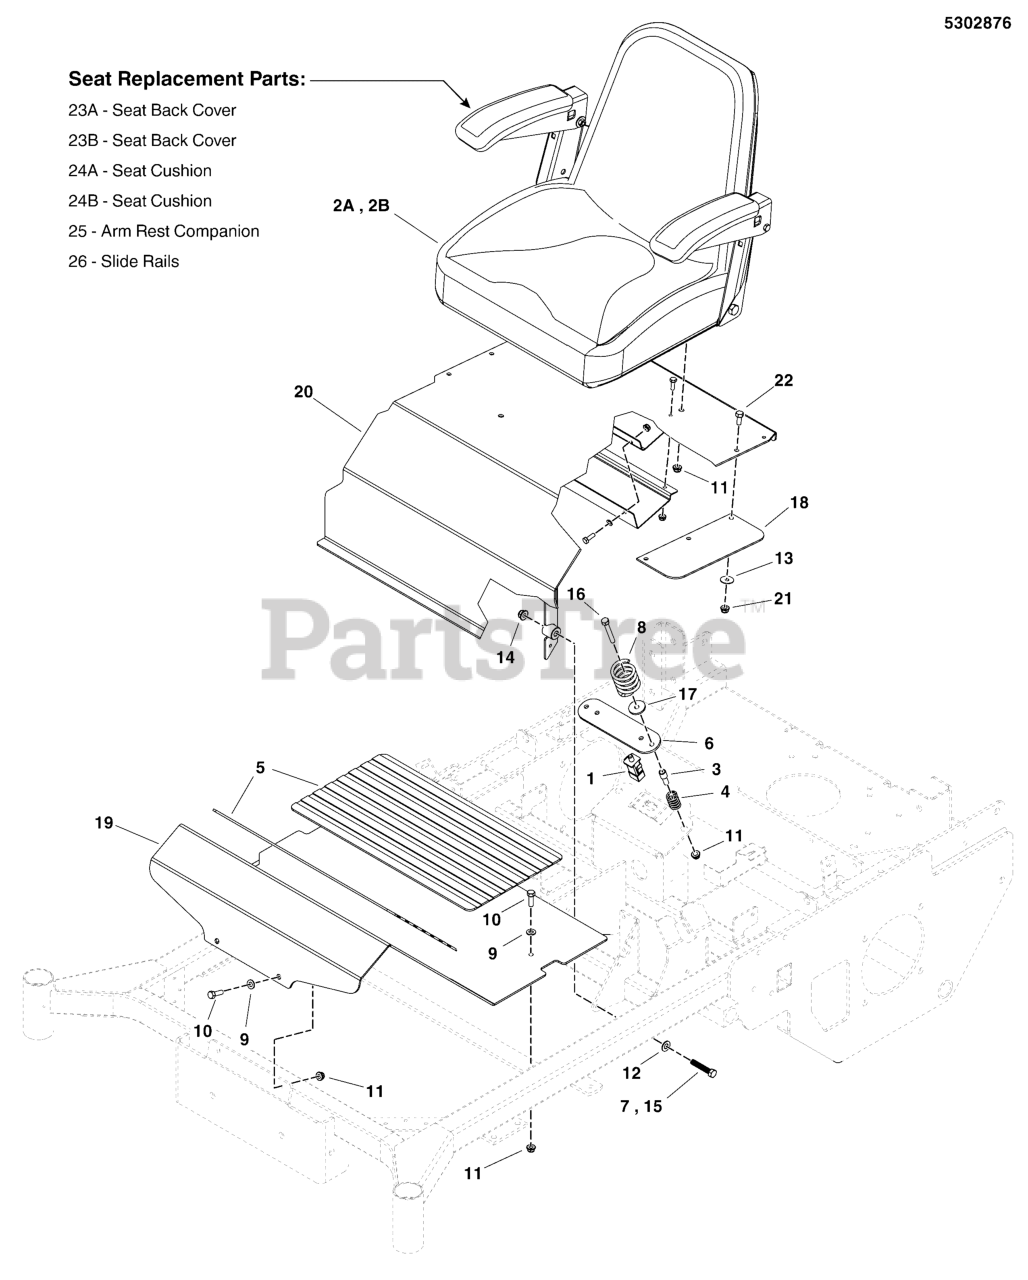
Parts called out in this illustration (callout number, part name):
1	SWITCH, PLUNGER, NO/NO SNAP-IN
2A	SEAT, 2012
2B	SEAT, LOW COMPANION
3	SPACER, .328 ID X .66, YZ
4	SPRING-COMP, .720ID X 1.310LG X .118 WIRE
5	SAFETY WALK, 10.00 X 19.00
6	PLATE, SEAT SWITCH - RED
7	BOLT, 3/8-16 X 3-1/2" GD5 CZ
8	SPRING, SEAT SUPPORT
9	WASHER, 5/16" SAE
10	BOLT, 5/16-18 X 1 GD5 YZ
11	NUT, 5/16-18 HEX NYLOCK FLANGE
12	WASHER, 3/8 SAE
13	WASHER, 1/4 FENDER
14	NUT, 3/8-16 HEX NYLOCK FLANGE
15	BOLT, 3/8-16 X 2-1/2" GD5 CZ
16	BOLT, 5/16-18 X 2-1/4 GD5 YZ
17	WASHER, .34 X 1.25 X 10 GA
18	PLATE, SEAT, RUBBER FLAP
19	PLATE, FLOOR PAN, SNP 61 - RED
20	ASSM, SEAT PLATE W/ DECAL, S200XT, FRS RED
21	NUT, 1/4-20 HEX NYLOCK FLANGE
22	BOLT,1/4-20X0.750,GR5,STD NECK,SQ,ZC/CL
23A	SEAT BACK COVER (2012)
23B	SEAT BACK COVER
24A	SEAT COVER
24B	SEAT CUSHION
25	ARM REST
26	SLIDE RAILS
